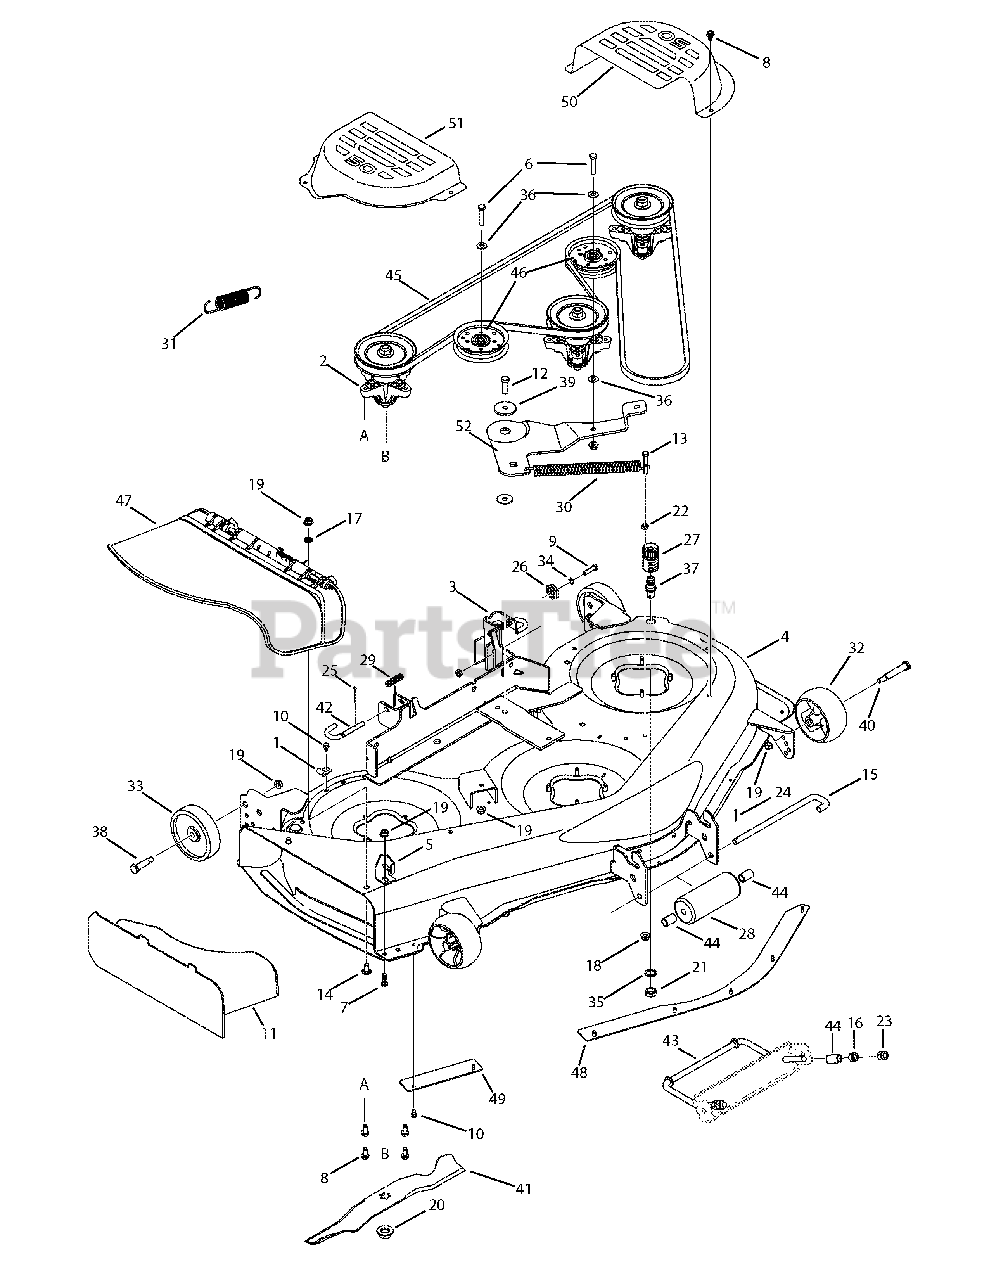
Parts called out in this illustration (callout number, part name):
1	Hook, Retainer
2	Spindle Assembly
6	Screw, 3/8-16, 1.75
7	Screw, 3/8-16 x 1.0
8	Screw, 5/16-18 x .75
9	Screw, 5/16-18, 1.25, Gr5
10	Screw, 1/4-20 x 0.5
11	Mulch Plug
12	Screw, 3/8-16, 1.25
13	Screw, 5/16-18 x 2.00
14	Screw, Carriage, 3/8-16 x .75
15	Roller Pin
16	Hex Nut, 1/2-13
17	Push Nut Retainer
18	Nut, Nylon Lock, 5/16-18
19	Nut, Nylon Lock, 3/8-16
20	Nut, Hex, Flange, 5/8-18
21	Nut, Hex, M16-1.5
22	Nut, Hex, 5/16-18, Gr5
23	Hex Lock Nut, 1/2-13
24	Pin, Cotter, 3/32 x 1.00
25	Pin, Cotter, 1/8 x 1.25
26	Deck Adjustment Gear
27	Coupler, Hose
28	Roller
29	Spring, Compression, .531 x 1.75
30	Spring, Extension, .94 x 6.74
31	Spring, Lift Assist
32	Deck Wheel, 5.0
33	Deck Wheel, 5.0
34	Washer, Lock, 5/16
35	Lock Washer, 5/8"
36	Washer, Flat, .406 x .875 x .059
37	Port, Water
38	Shoulder Screw
39	Spacer, Shoulder, .884 x .190
40	Shoulder Screw
41	Blade, 17.90
42	Rod, Deck Release .375 Dia.
43	Rod, Deck Adjust
44	Spacer, .550 x .750 x 1.125
45	Belt, V-Type
46	Pulley, Idler, 3.5"
47	Chute Assembly, Side Discharge
